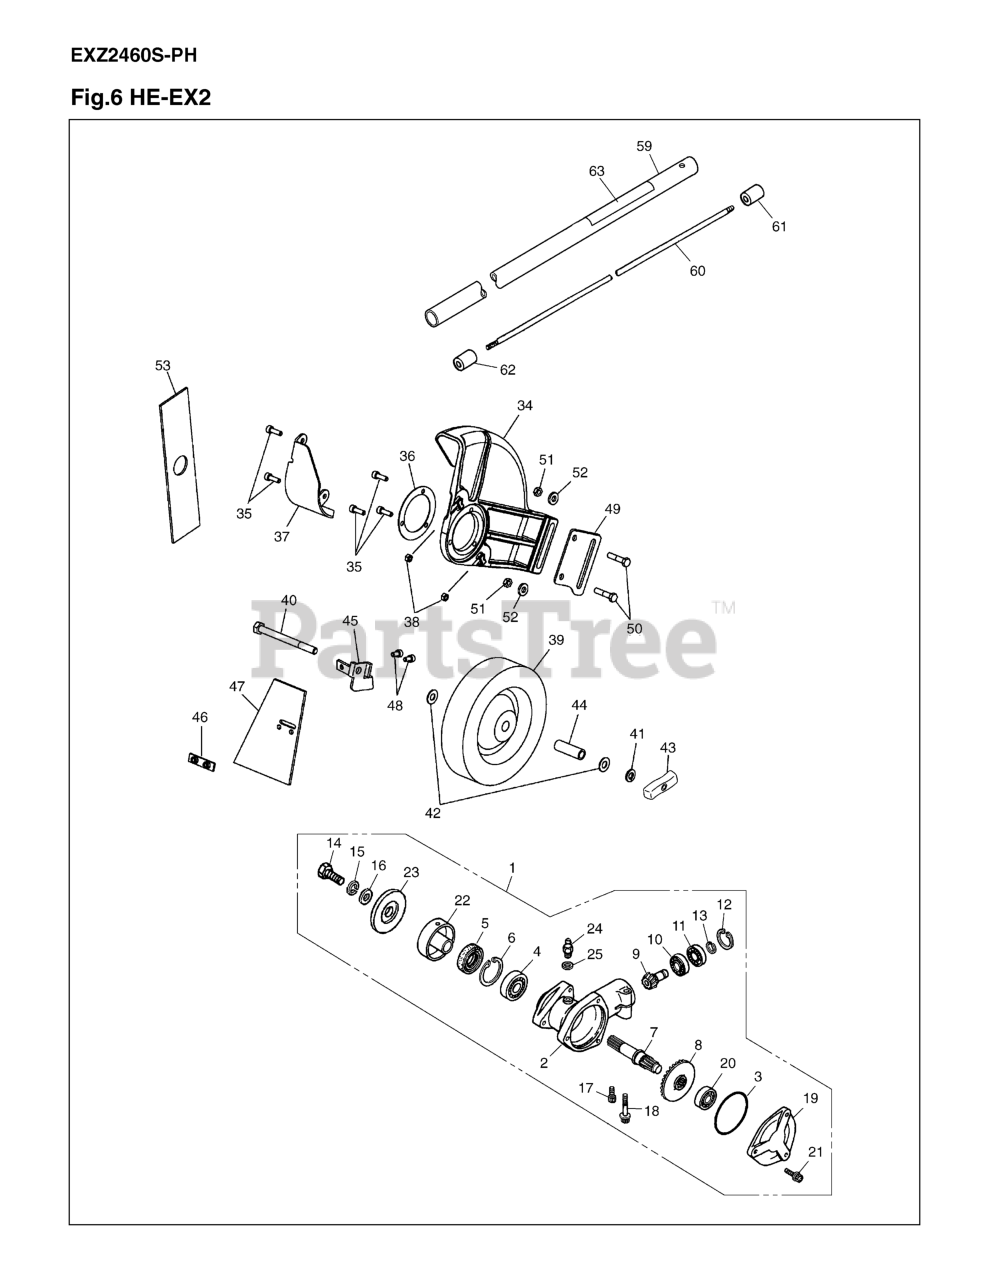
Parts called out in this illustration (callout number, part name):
1	GEARCASE
2	GEARCASE
3	O-RING
5	SEAL, OIL
7	SHAFT, GEAR (-13
9	PINION
10	BEARING (RPLS T3
12	RING, SNAP, M24
13	RING, SNAP (RPLS
14	BOLT, LH
15	WASHER (RPLS 318
16	WASHER,M8x2.3(RP
17	BOLT, M5 x 12
18	BOLT, M6 x 1.35
19	COVER
20	BEARING (RPLS 06
22	HOLDER (A)(RPLS
23	HOLDER (B)
24	FITTING, GREASE
25	WASHER, M6 x .8
34	Guard
35	BOLT (M5x0.8-16)
37	PROTECTOR
38	NUT, M5 x 4
39	WHEEL (RPLS T305
40	BOLT
41	WASHER, SPRING(T
42	WASHER
47	RUBBER (FLAP)
48	BOLT, M5 x 10
49	MAIN BRACKET
50	BOLT
52	WASHER
53	BLADE, EDGER (RP
59	PIPE COMPLETE
61	JOINT, SHAFT (RP
62	SPACER
63	PLATE-NAME
